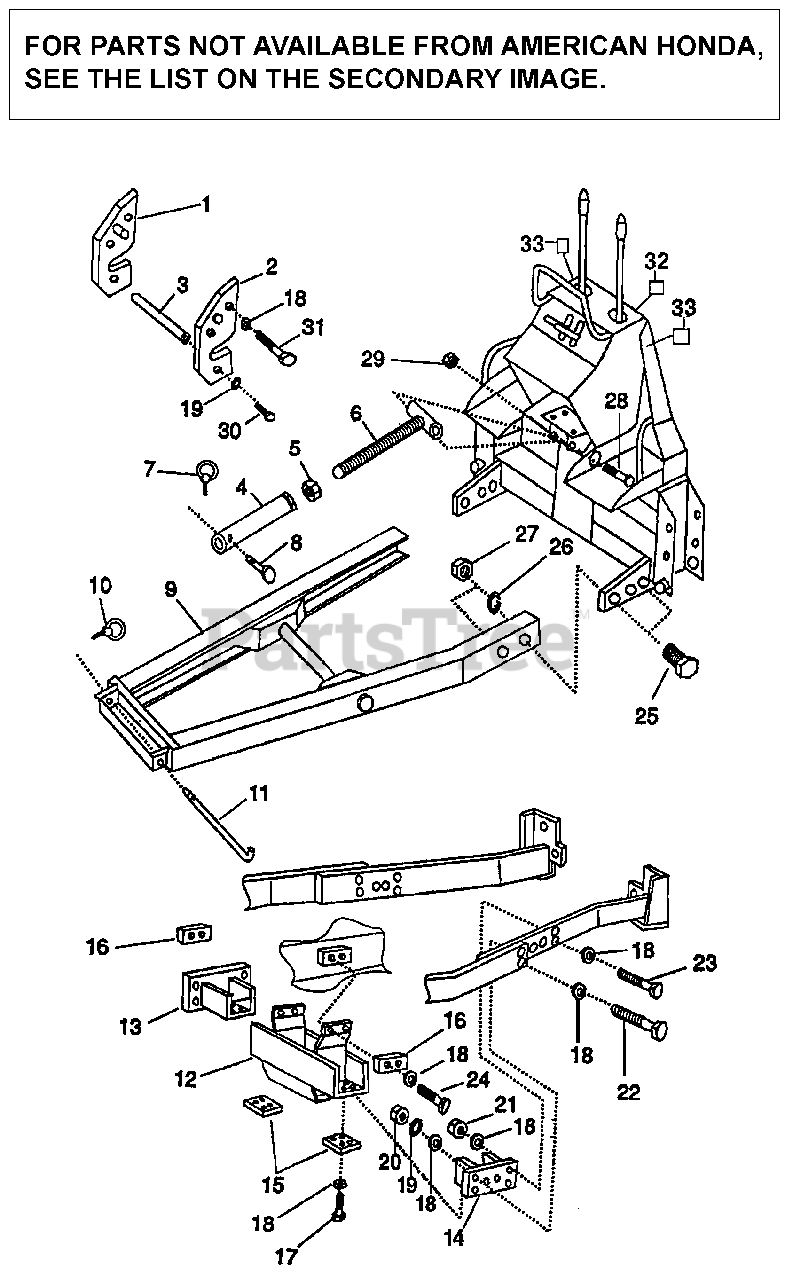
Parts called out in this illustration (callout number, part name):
1	BRACKET, R. RR. SELF MOUNTING
2	BRACKET, L. RR. SELF MOUNTING
3	SHAFT, CROSS (1X11.8)
4	LINK (UPPER) (OUTER)
6	LINK (UPPER) (INNER)
11	PIN (19X397)
12	PLATE, CROSSMEMBER (NOT AVAILABLE)
13	BRACKET, R. CROSSMEMBER
14	BRACKET, L. CROSSMEMBER
24	BOLT (12X35)
31	BOLT (12X80)
32	LABEL, WARNING
33	LABEL, DANGER
